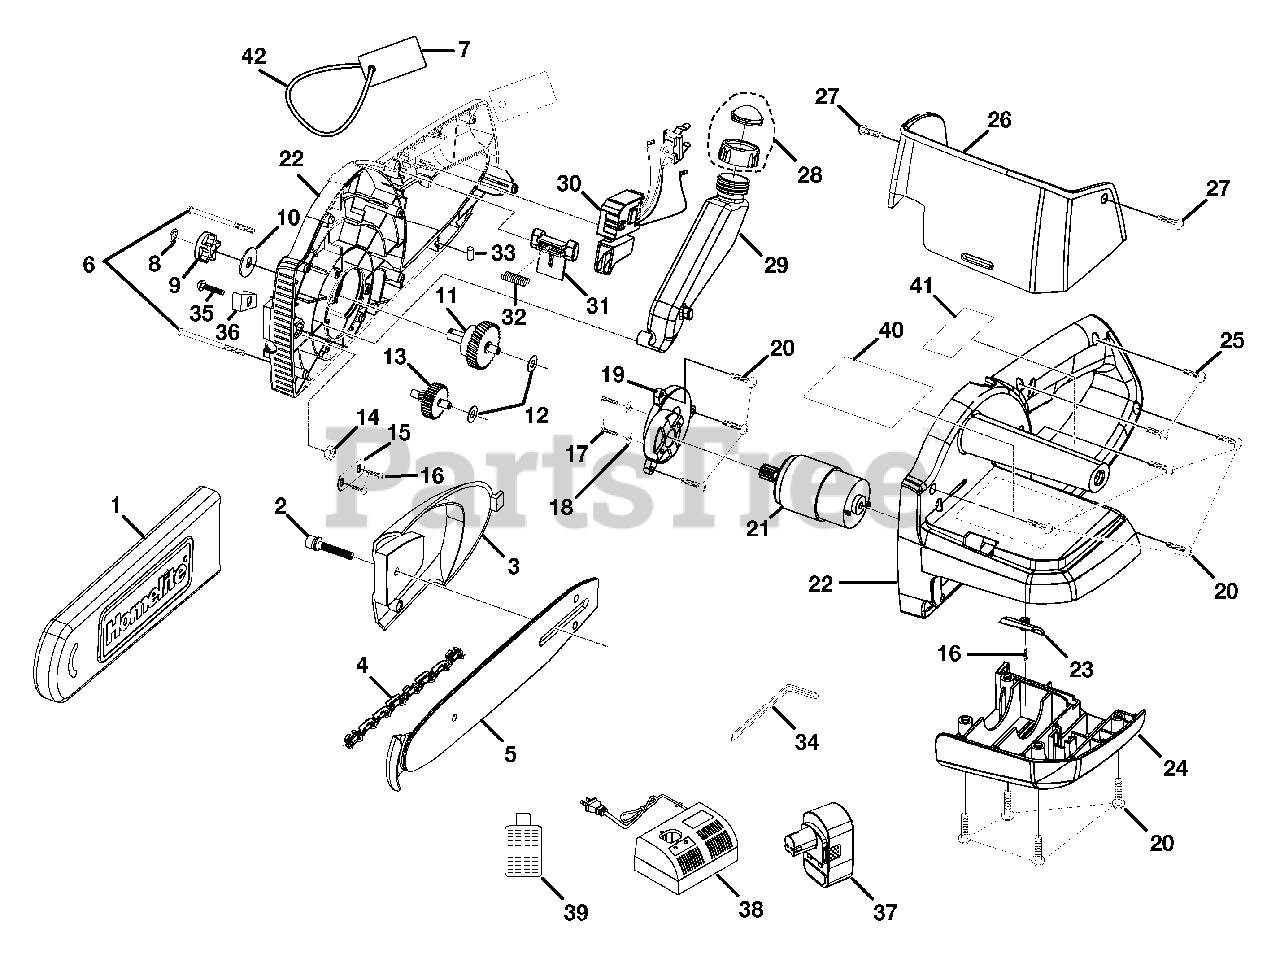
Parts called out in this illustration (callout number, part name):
2	SCREW (SOCKET HEAD)
3	SPROCKET GUARD
4	CHAIN, (90JG-040)
5	CHAIN BAR (10 in.)
6	SCREW (M4 X 66 mm)
7	WARNING LABEL (ON HANDLE)
9	SPROCKET
10	COVER PLATE
11	OUTPUT SHAFT ASSEMBLY
13	OUTPUT SHAFT ASSEMBLY
15	STEEL PLATE
16	BEARING RETAINER SCREW
17	SCREW (M4 X 12 mm)
18	SPRING WASHER
19	MOTOR MOUNTING ASSEMBLY
20	SCREW (M4 X 22 mm PAN HD.)
21	MOTOR ASSEMBLY
22	MOTOR HOUSING SUPPORT
23	WIND PLATE
24	LOWER MOTOR HOUSING
25	SCREW (M4 X 16 mm PAN HD.)
26	FRONT HANDLE GUARD
27	SCREW (M3.5 X 25 mm)
28	OIL TANK COVER ASSEMBLY
29	OIL TANK
30	SWITCH ASSEMBLY
31	SAFETY KNOB
33	CONTACT PLATE STOPPER
34	HEX KEY (5 mm)
35	SCREW (M2.3 X 6 mm)
36	FELT SEAL
37	BATTERY
38	BATTERY CHARGER
39	OIL AND BOTTLE ASSEMBLY
40	WARNING LABEL
41	RATING LABEL
42	CABLE TIE
